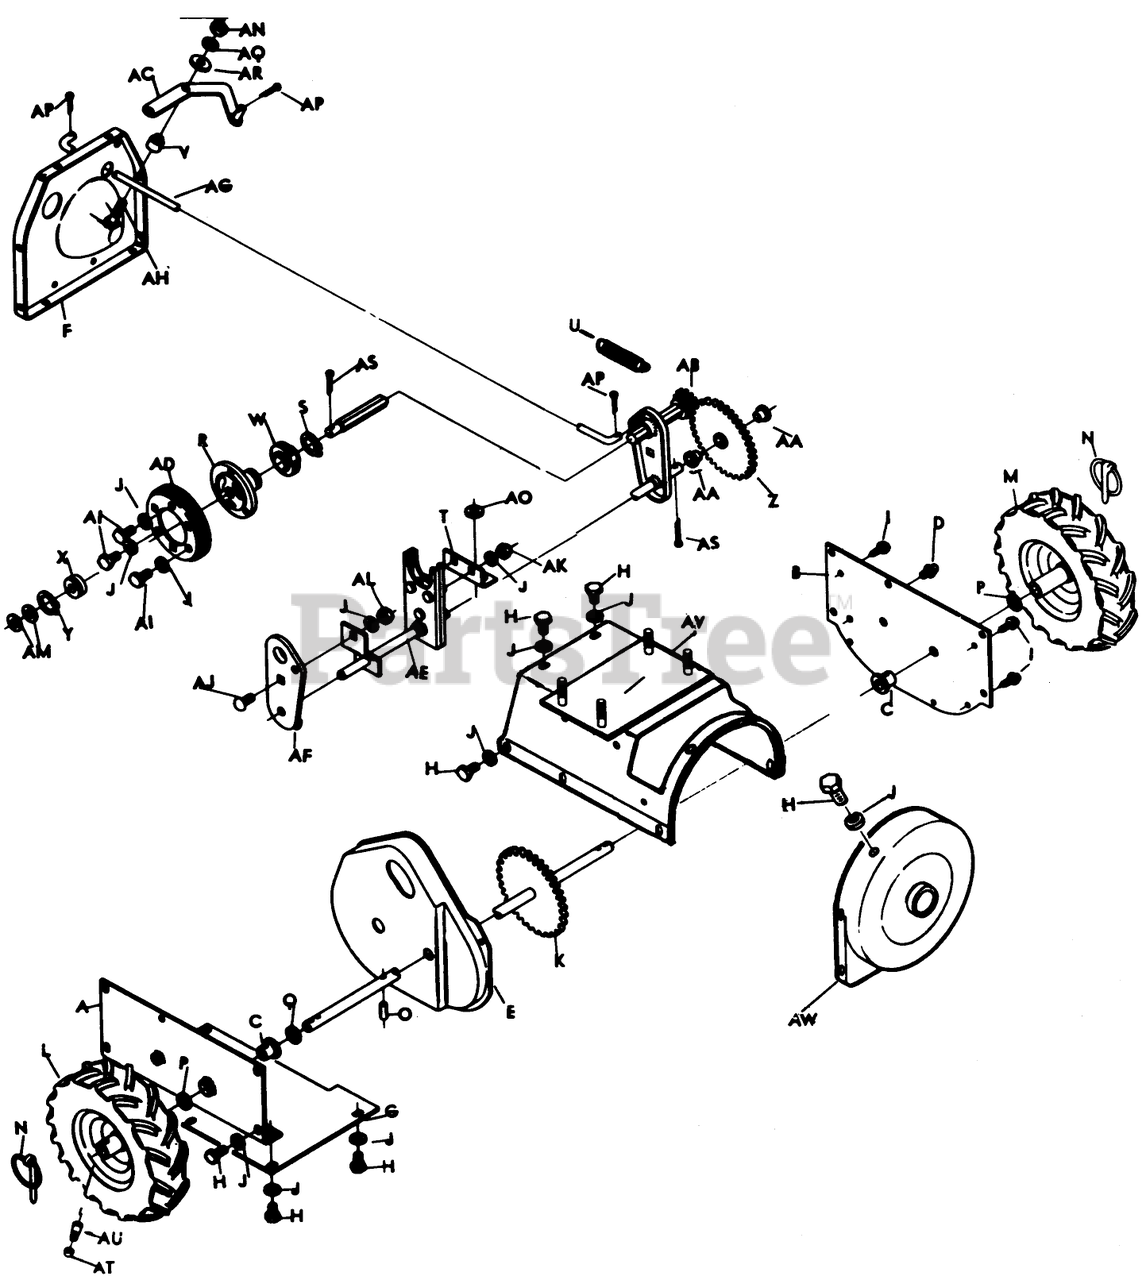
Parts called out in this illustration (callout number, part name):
H	5/16-18 x 3/4 Hex. Hd. Cap Screw, Pl.
J	5/16 Lock Washer, Pl.
L	Tire Wheel Ass-y, R.H., 5 H.P. Units
O	1/8 x 1 1/4 Roll Pin
Z	Countershaft Gear Assembly
AH	3/8-16 X 1 3/4 Hex. Hd. Cap Screw, Pl.
AI	5/16-18 x 1/2 Hex. Hd. Cap Screw, Pl.
AJ	5/16-18 X 1/2 Carriage Bolt, Pl.
AK	5/16-18 Hex. Cone Lock Nut, Pl.
AL	5/16-18 Hex. Nut, Pl.
AN	3/8-16 Cone Lock Nut, Pl.
AO	S.A.E. Flat Washer
AP	1/8 x 3/4 Cotter Pin, Pl.
AQ	3/8 Lock Washer, Pl.
AS	1/8 x 1 Cotter Pin, Pl.
AV	Main Frame Ass-y, 5 H.P. Units
AW	Cover Plate Assembly
